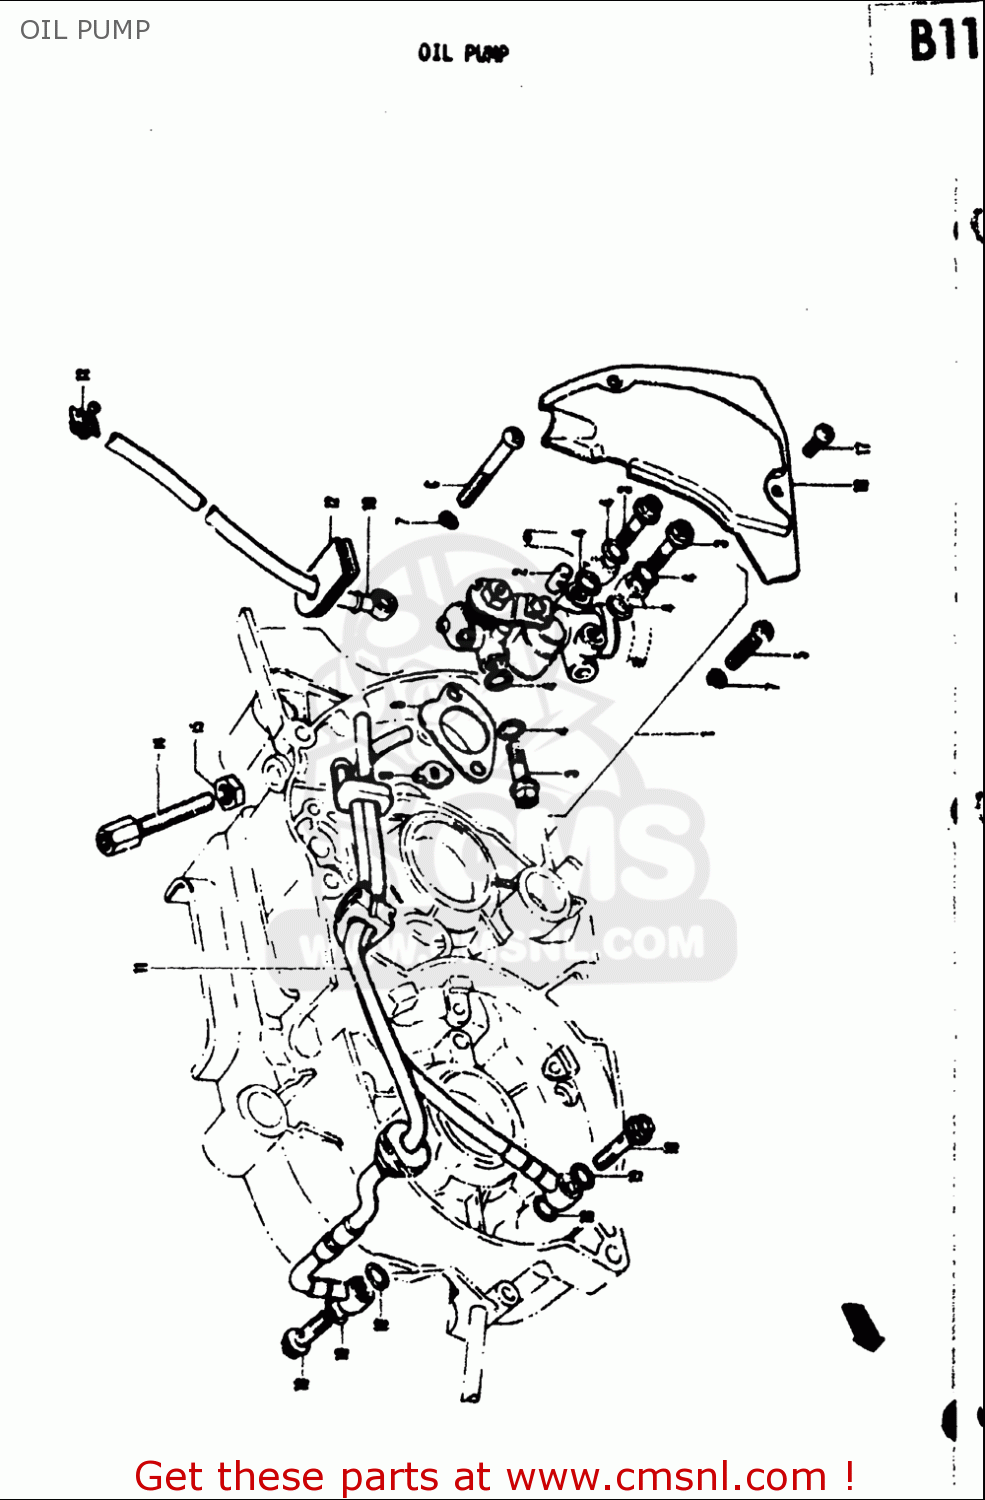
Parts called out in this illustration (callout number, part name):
2	TERMINAL,CABLE
3	UNION BOLT
4	GASKET(6.2X11X1).2 (NAS)
5	SCREW
6	SCREW
7	WASHER,LOCK
8	GASKET,OIL PUMP (NAS)
9	PIECE,OIL PUMP DRIVE
10	HOSE,INLET
11	HOSE,OIL NO.2
12	GROMMET
13	CLAMP
14	BOLT
15	NUT
16	CAP,OIL PUMP INSPECTION
17	SCREW
18	UNION BOLT
19	GASKET(6.2X11X1).2 (NAS)
